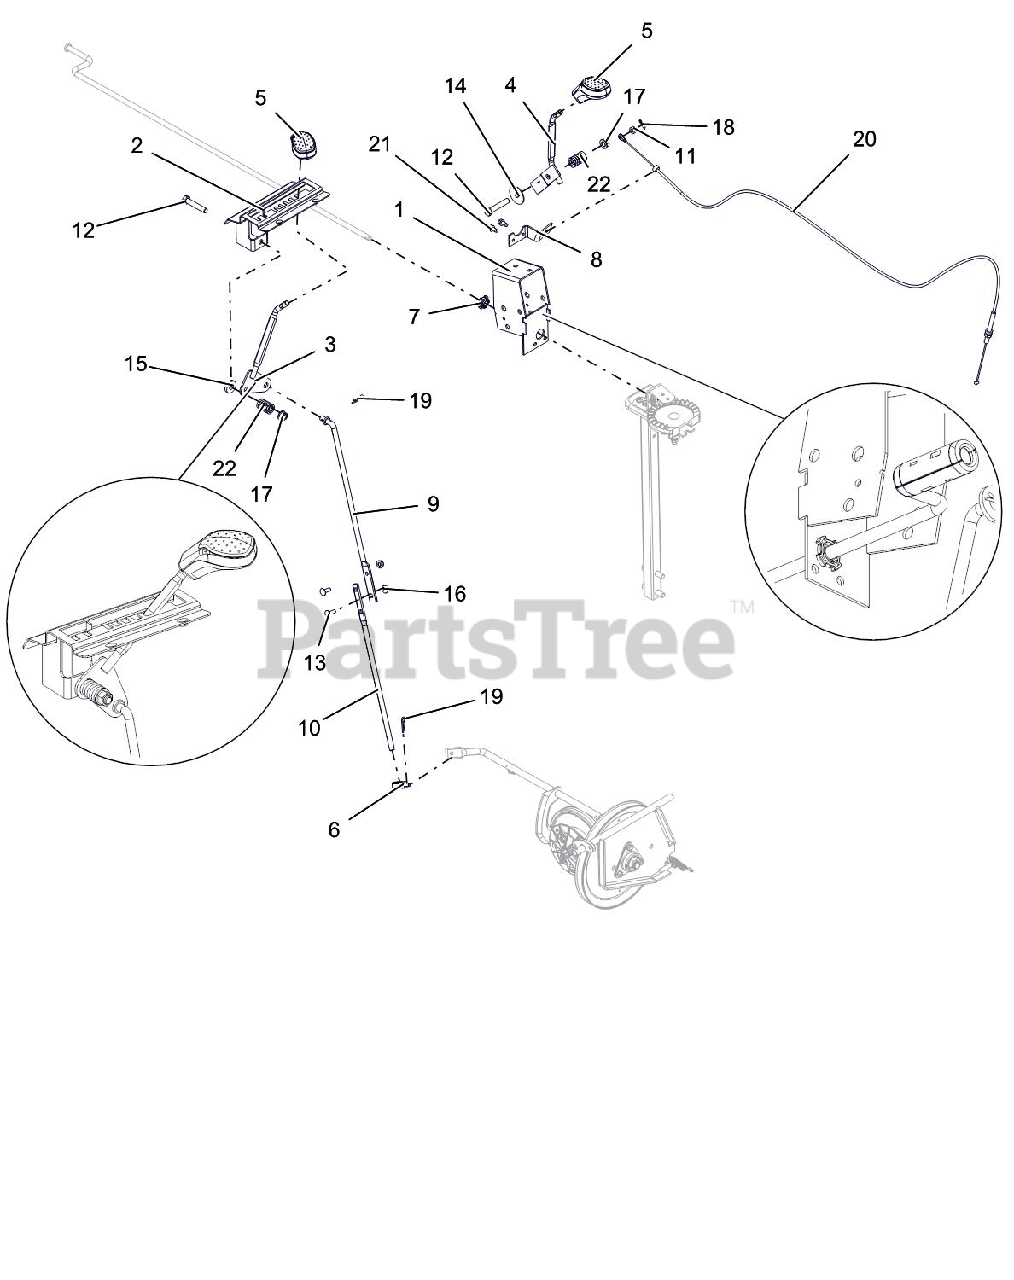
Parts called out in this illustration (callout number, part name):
1	WELDMENT, BRACKET INTERLOCK
2	WELDMENT, DETENT PLATE-COMPACT
3	LEVER, CONTROL-SHIFT(WELDMENT)
4	WELDMENT,SM DASH DEFL CONTROL
5	KNOB, CONTROL, DASH
6	PIVOT,SHIFT ROD .375-16(TRUNN)
7	CRANK BUSHING, NYLON CHUTE BK
8	ANCHOR, DEFLECTOR CABLE
9	ROD, SHIFT - UPPER
10	ROD, SHIFT - LOWER(SMALL DASH)
11	BSHG-SLV .265X.500X.219
12	@BLT-HEX .38-16X2.00 GR5 YWZC
13	@BLT-RDHDSQNK .25-20X.75 G5YZ
14	WSHR-FL-STL .380X1.50X.062 YWZ
15	WSHR-FL-STL .406X1.00X.188 YWZ
16	@NUT-LK-CTR-FLG .25-20 YWZC
17	@NUT-LK-TOP-FLG .38-16 YWZC
18	PIN-HAIR INT .06X.18X.77
19	PIN-HAIR INT .08X.18X1.18 YWZC
20	CABLE, DEFLECTOR - COMPACT
21	SCR-TAP .25-20X.50 HWH TR YWZ
22	SG-COMP .125X.781X1.250
